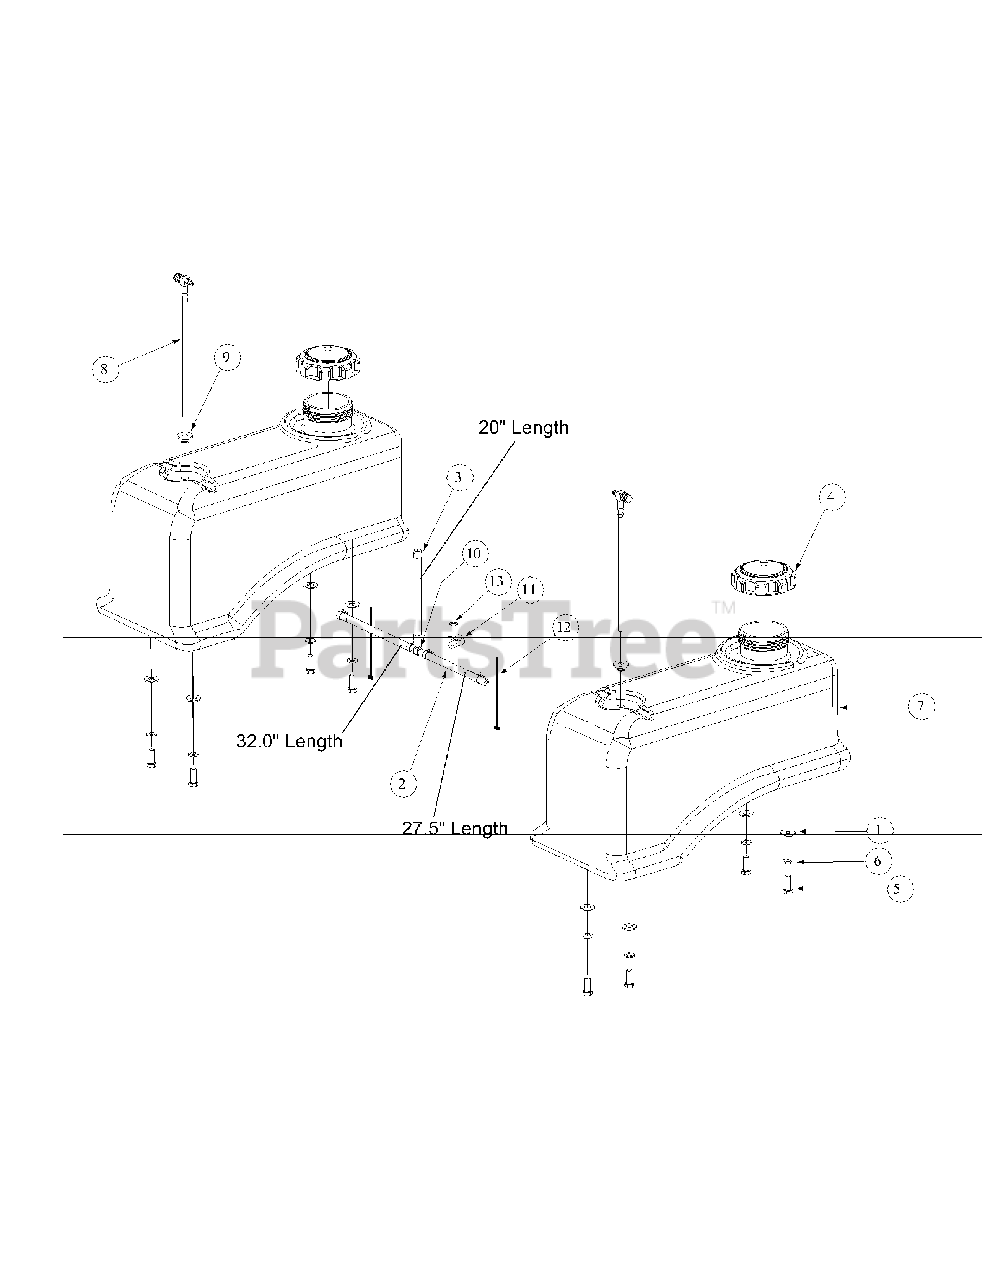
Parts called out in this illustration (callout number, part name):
1	Flat Washer, .406 ID, 1.0 OD, .105
2	Hose, 1/4" Fuel Line, 79.5"
3	Clamp, Union
4	Fuel Cap, 3.5
5	Hex, Cap Screw, 3/8-16, .88
6	Lock Washer, 3/8
7	Fuel Tank
8	Fuel Fitting
9	Fuel Tank Grommet
10	Tee Fitting, Fuel
12	Cable Tie
13	Flatwasher 1/4 x .630 x .0515
